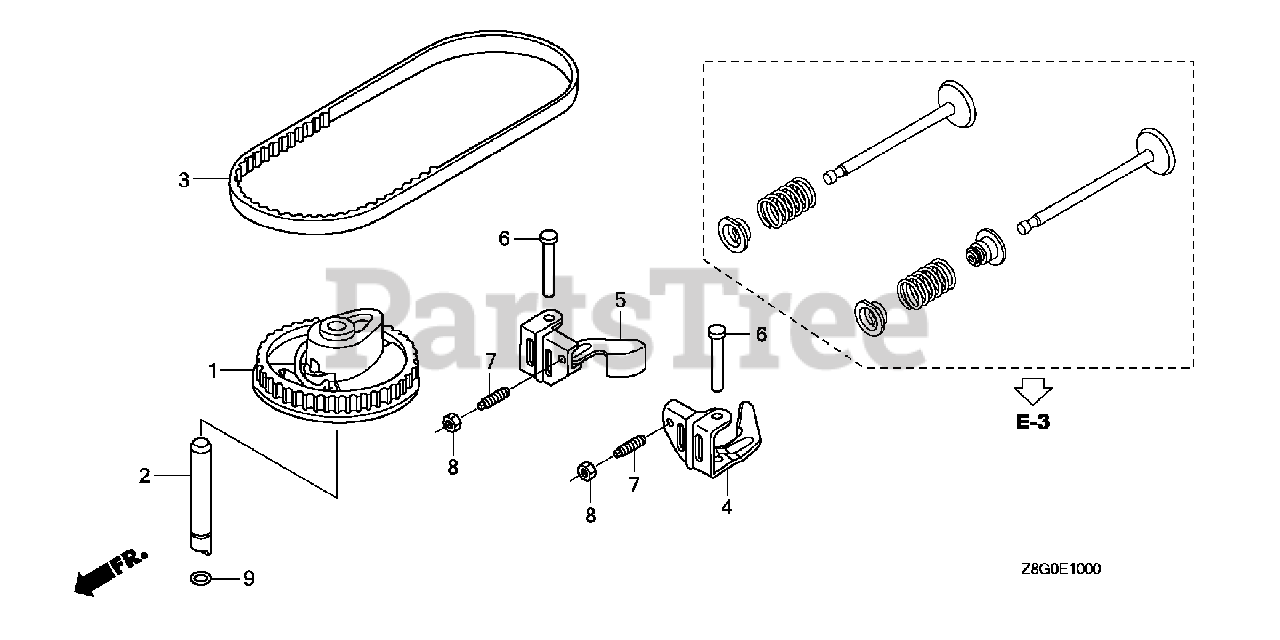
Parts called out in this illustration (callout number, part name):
1	PULLEY, CAMSHAFT
2	SHAFT, CAM PULLEY
3	BELT, TIMING (84HU7 G-200)
4	ARM, IN. VALVE ROCKER
5	ARM, EX. VALVE ROCKER
6	SHAFT, ROCKER ARM
7	SCREW, TAPPET ADJUSTING
8	NUT, TAPPET ADJUSTING
9	O-RING (6.8X1.9) (ARAI)
